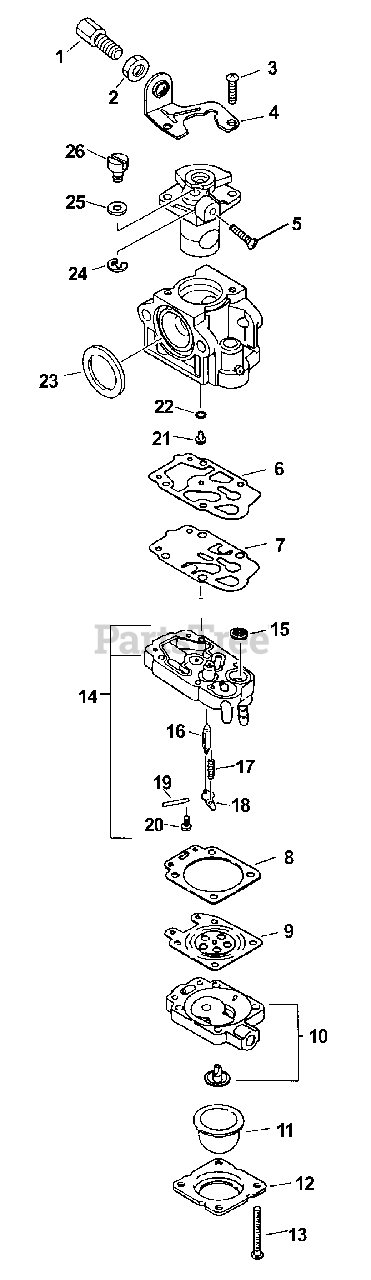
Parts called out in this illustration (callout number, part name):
1	ADJUSTER, THROTTLE CABLE
2	NUT, ADJUSTER LOCK M7
4	BRACKET, THROTTLE CABLE
6	GASKET, PUMP
7	DIAPHRAGM, PUMP
8	GASKET, METERING
9	DIAPHRAGM, METERING
10	BODY ASSY, PURGE
11	BULB, PURGE
12	RETAINER, PURGE BULB
14	BODY ASSY, PUMP
15	STRAINER
16	VALVE, INLET NEEDLE
17	SPRING, METERING LEVER
18	LEVER, METERING
19	PIN, METERING LEVER
21	JET, MAIN
23	SEAL
26	REPAIR KIT
26	DIAPHRAGM KIT
